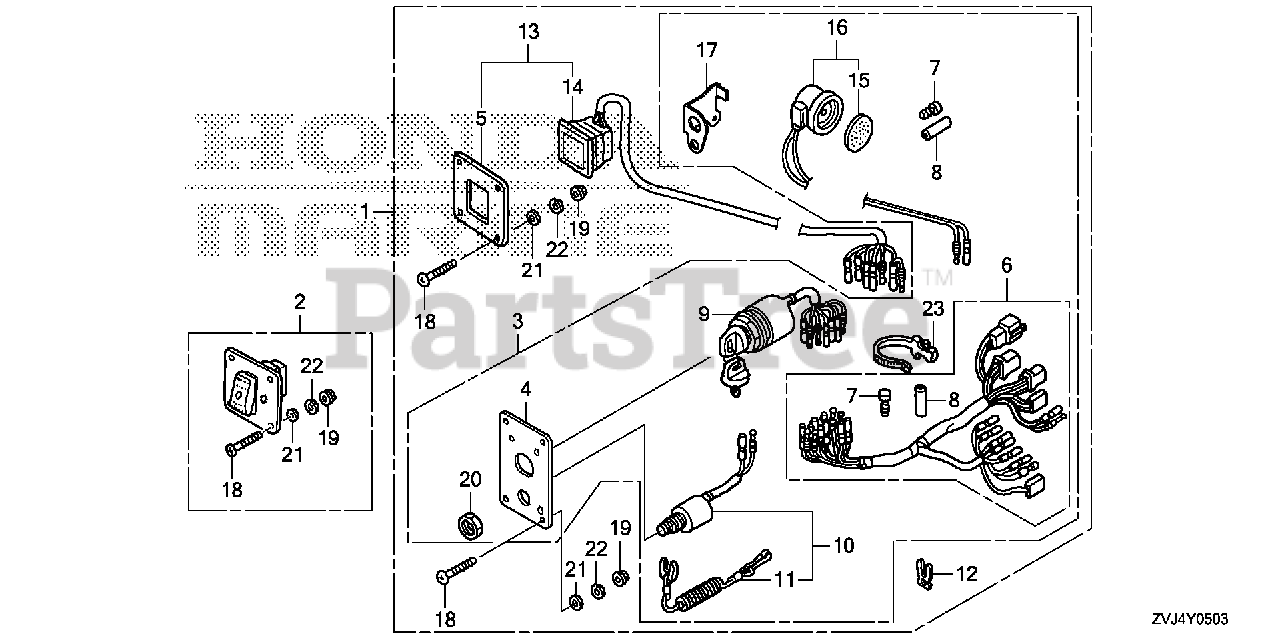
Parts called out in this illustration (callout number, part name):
1	PANEL KIT, SWITCH (4-LED) (B)
2	SWITCH KIT, LIGHT
3	PANEL ASSY., SWITCH
4	PANEL, CONTROL
5	PANEL, CONTROL
6	HARNESS ASSY., SWITCH PANEL
7	PLUG, CONNECTOR (INNER)
8	PLUG, CONNECTOR (OUTER)
9	SWITCH ASSY., COMBINATION
10	SWITCH ASSY., EMERGENCY STOP
11	WIRE, EMERGENCY
12	CLIP, EMERGENCY LOCK
13	PANEL ASSY., INDICATOR (4-LED)
14	LAMP ASSY., INDICATION (4-LED)
15	PLATE, TURN SIGNAL BUZZER
16	BUZZER, WARNING
17	BRACKET, BUZZER
18	SCREW, PAN (5X40)
19	NUT, FLANGE (5MM)
20	NUT, HEX. (16MM)
21	WASHER, PLAIN (5MM)
22	WASHER, SPRING (5MM)
23	BAND, WIRE HARNESS (150MM) (NATURAL)
